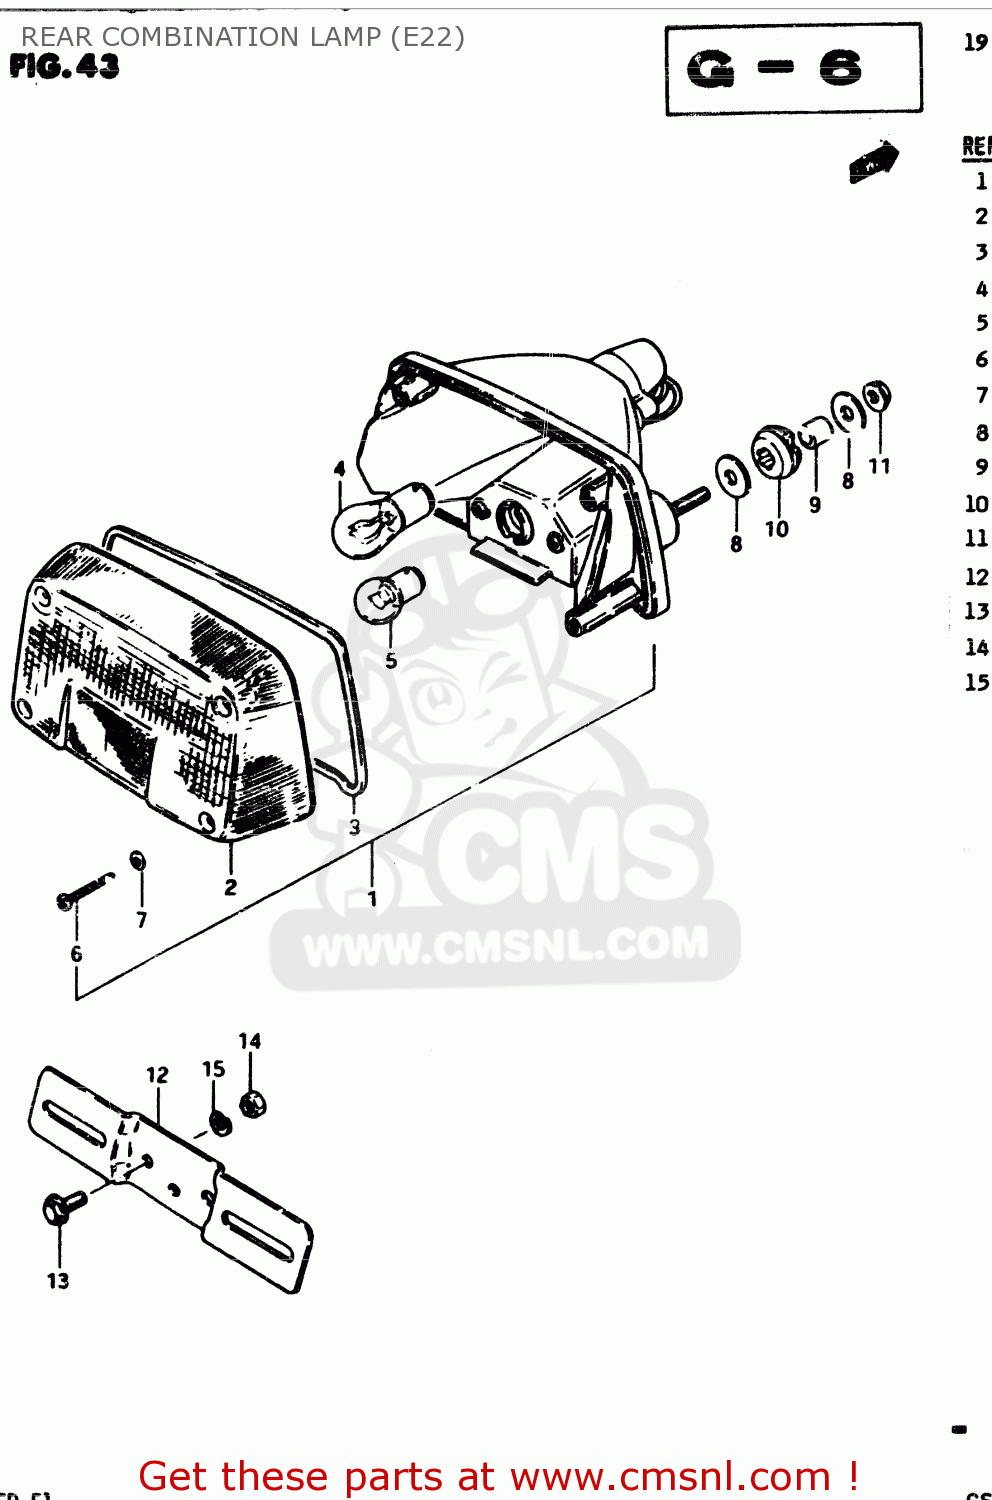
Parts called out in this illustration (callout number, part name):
1	LAMP ASSY, REAR COMBINATION
2	LENS,REAR COMBINATION LAMP
3	GASKET
4	BULB(12V21/5W)
5	BULB
6	SCREW
7	GASKET (NAS)
8	WASHER
9	SPACER (6.8X10X11.5)
10	CUSHION
11	NUT 6MM
12	BRACKET, LICENSE PLATE
13	BOLT
14	NUT
15	LOCK WASHER
